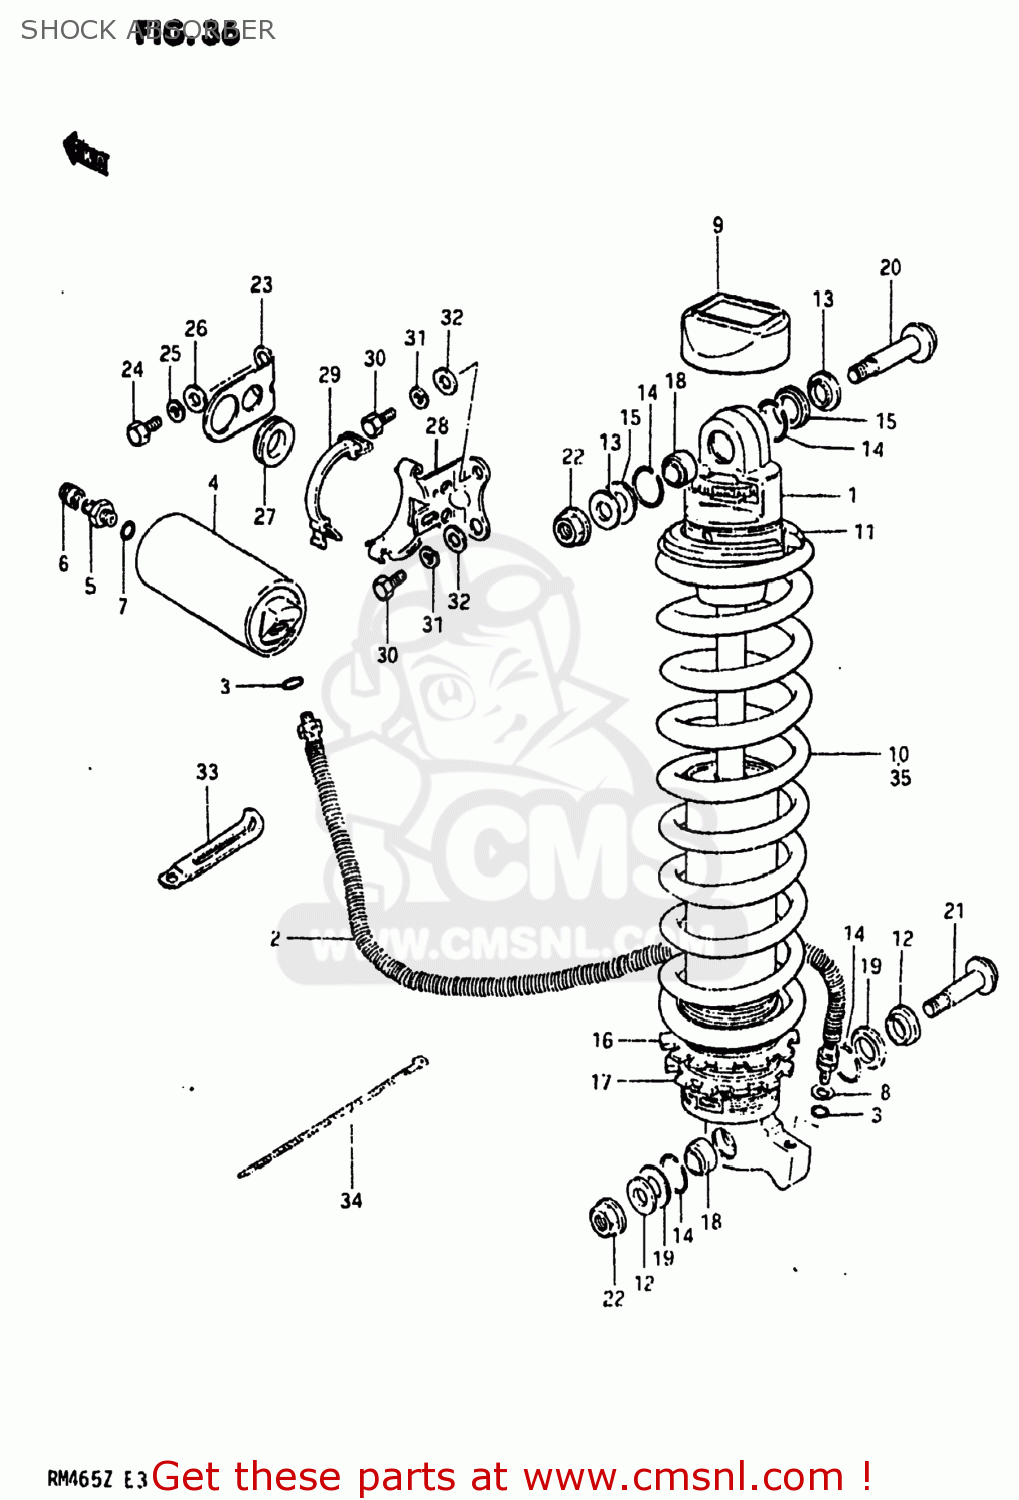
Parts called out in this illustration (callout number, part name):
1	ABSORBER ASSEMBLY,REAR SHOCK
2	HOSE,REAR SHOCK ABSORBER
3	O-RING,RESERVE TANK
4	RESERVE TANK,REAR SHOCK
5	VALVE ASSEMBLY,REAR CUSHION
6	CAP,VALVE AIR
7	O RING
8	WASHER,REAR SHOCK HOSE
9	CAP REAR SHOCK
10	SPRING
11	SPRING, GUIDE
12	COLLAR
13	SPACER,REAR SHOCK,UPPER
14	RING
15	DUST SEAL,UPR
16	GUIDE,SPRING
17	GUIDE,REAR SHOCK ABSORBER SPRING
18	BEARING
19	DUST SEAL,LWR
20	BOLT
21	BOLT(10X54)
22	NUT
23	BRACKET,RESERVOIR TANK
24	BOLT
25	LOCK WASHER
26	WASHER
27	CUSHION,RESERVOIR TANK
28	BRACKET,RESERVOIR TANK
29	BAND
30	BOLT
31	LOCK WASHER
32	WASHER
33	CLAMP
34	CLAMP
35	SPRING
